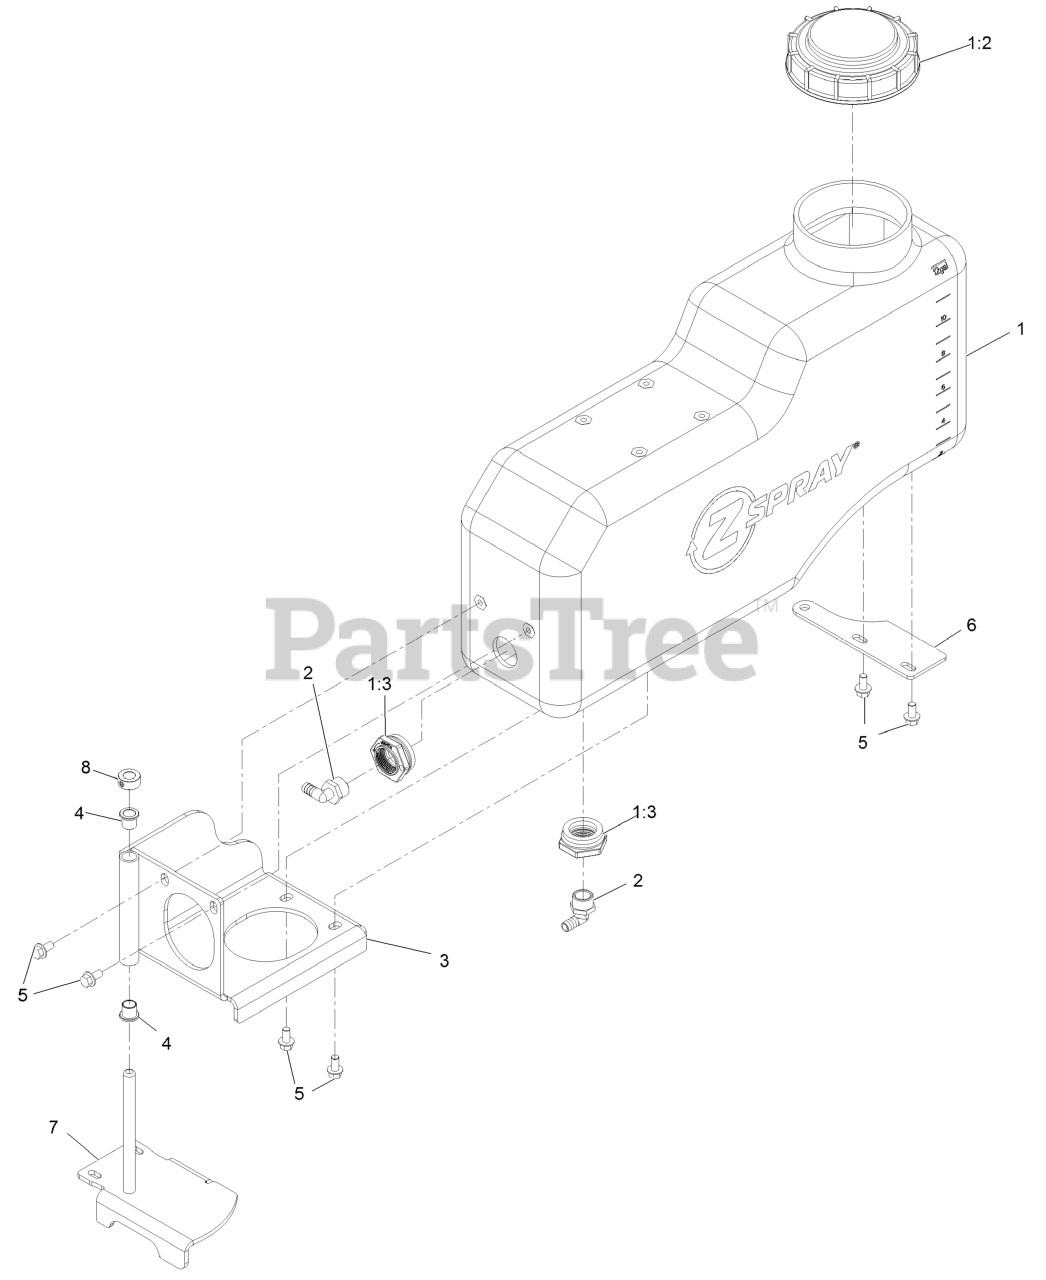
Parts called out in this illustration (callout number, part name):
1	ASM-TANK, LT
1:2	CAP-TANK, SPRAY
1:3	FITTING-BULKHEAD
2	FITTING-ELBOW, 90
3	WLD, WING, TANK, BOTTOM,
4	BUSHING-FLANGE
5	SCREW-HHF
6	PLATE, PIVOT LOCK, TANK, JR36
7	WLD, WING, TANK, BOTTOM,
8	5/8 SHAFT COLLAR
